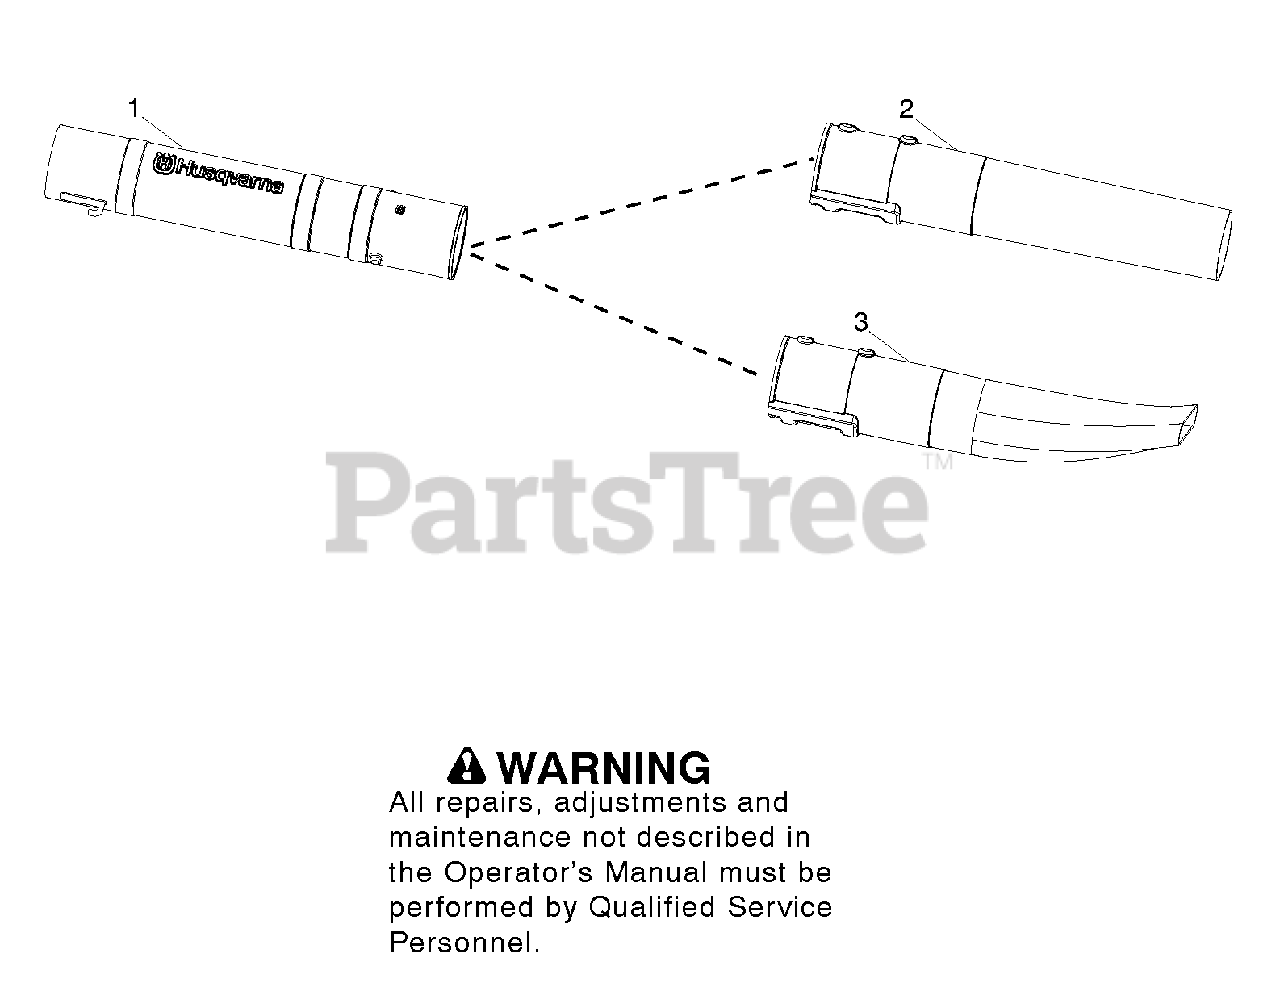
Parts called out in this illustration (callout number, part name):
1	Assy - Tube - Upper Blower w/barrier
2	Tube - Lower blower (round)
3	Tube - Lower blower (flare)
